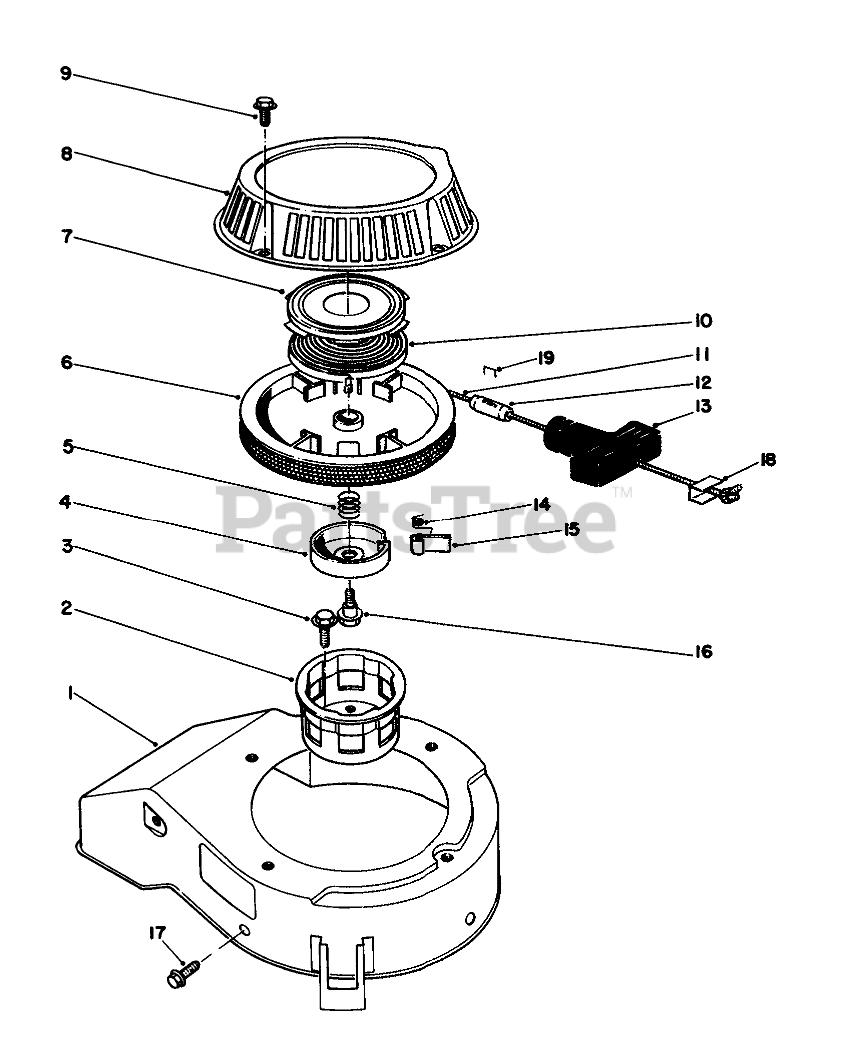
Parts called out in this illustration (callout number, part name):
1	COVER
2	CUP - STARTER
4	RETAINER
5	SPRING
7	Retainer-Recoil Spring
9	SCREW-HHF
10	Spring-Recoil
11	ROPE-STARTER
13	HANDLE-RECOIL
14	SPRING
18	Insert Handle
19	STAPLE
